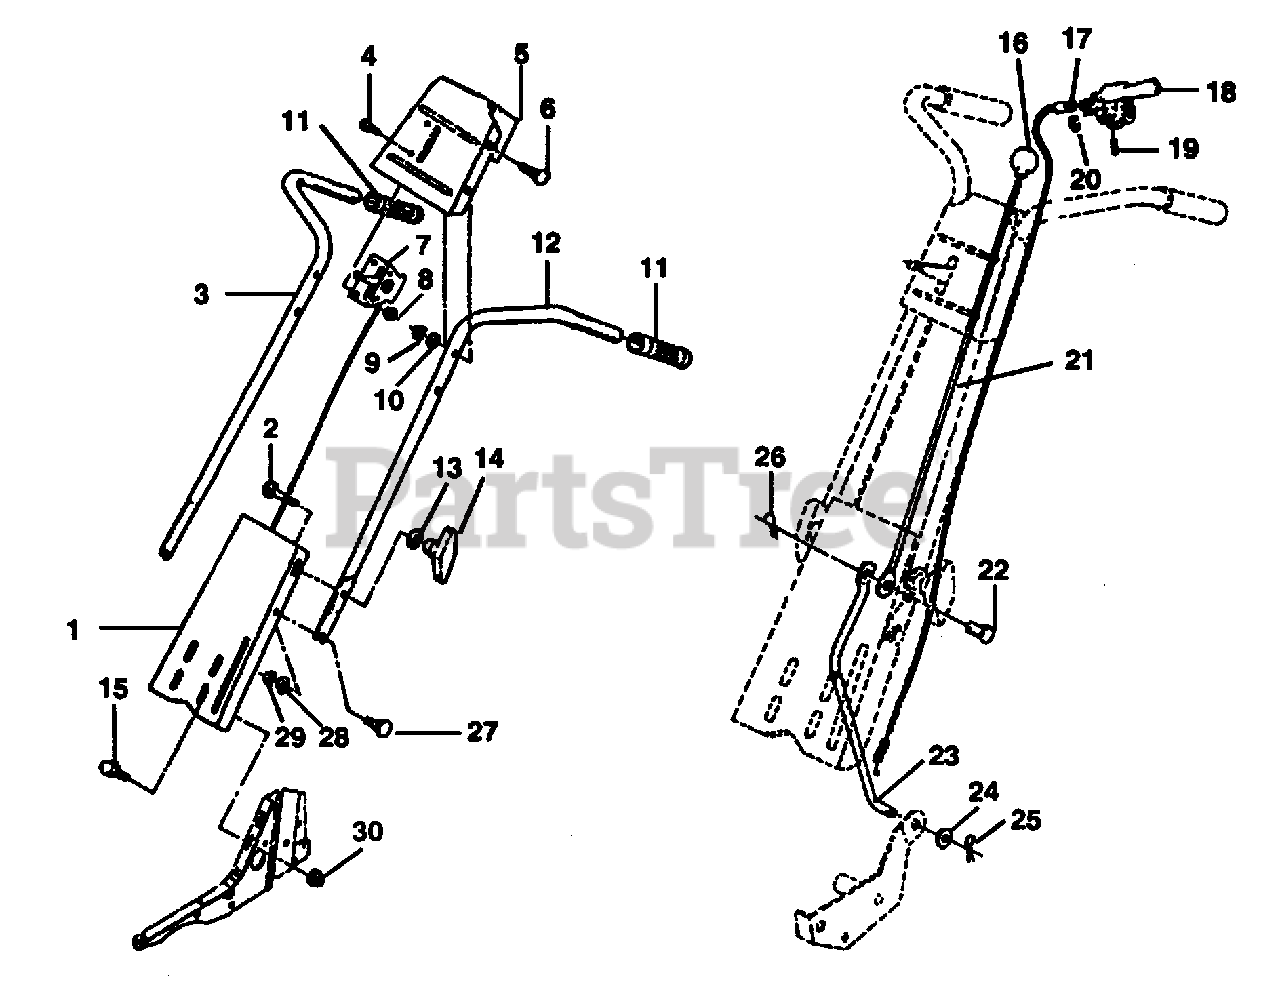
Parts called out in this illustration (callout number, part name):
1	Panel, Handle (AYP part number)
2	Bolt, Carriage 5/16-18 x 1-1/4 Gr. 5 (AYP part number)
3	Handle, R.H. (AYP part number)
4	Screw, Machine, Pan Hd. CR #10-24 UNC x 1/2 (AYP part number)
5	Bracket, Handle (AYP part number)
6	Bolt, Carriage 5/16-18 UNC x 1-1/4 (AYP part number)
7	Control, Throttle (AYP part number)
8	Nut, Keps #10-24 UNC (AYP part number)
9	Locknut, Crown 5/16-18
10	Washer 11/32 x 11/16 x 16 Ga. (AYP part number)
11	Grip, Handle (AYP part number)
12	Handle, L.H. (AYP part number)
13	Washer 3/8 x 7/8 x 14 Ga. (AYP part number)
14	Knob, Handle (AYP part number)
15	Bolt, Carriage 5/16-18 x 3/4 Gr. 5
16	Knob, Control, Reverse (AYP part number)
17	Cable, Control, Tine (AYP part number)
18	Lever, Control, Tine (AYP part number)
19	Screw, Set, Socket, Forged, Headless 1/4-20 x 5 (AYP part number)
20	Ring, Klip (AYP part number)
21	Rod, Reverse, Upper (AYP part number)
22	Pin, Retaining (AYP part number)
23	Rod, Reverse, Lower (AYP part number)
24	Washer 13/32 x 13/16 x 16 Ga. (AYP part number)
25	Pin, Cotter 1/8 x 3/4 (AYP part number)
26	Pin, Cotter 3/32 x 1/2 (AYP part number)
27	Bolt, Shoulder 5/16-18 x 3/4 (AYP part number)
28	Washer, Lock 5/16 (AYP part number)
29	Nut, Hex 5/16-18 (AYP part number)
30	Nut, Flanged 5/16-18 (AYP part number)
